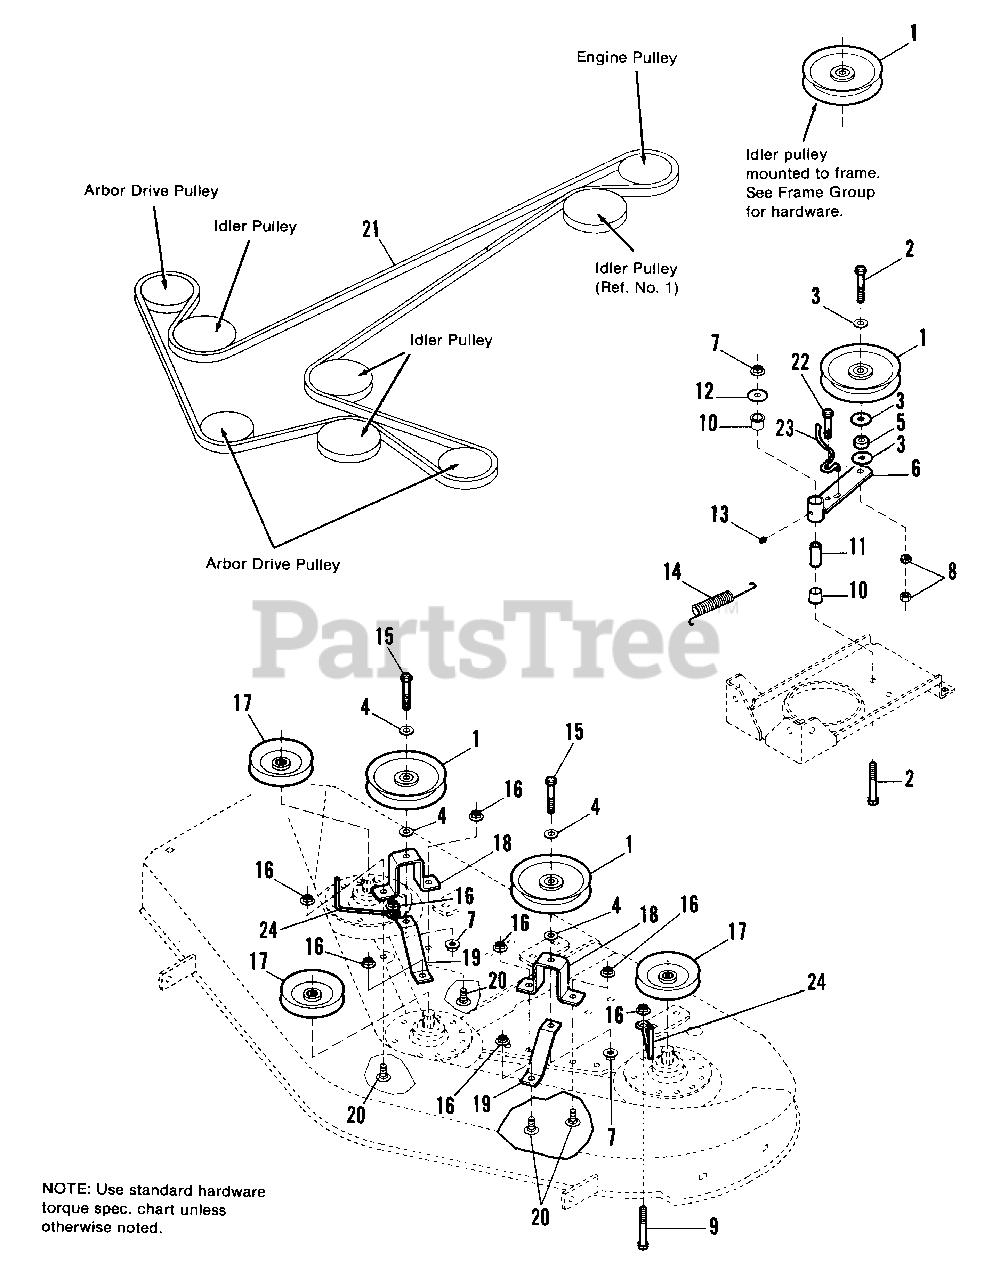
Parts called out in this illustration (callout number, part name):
1	PULLEY ASSY.
2	CAPSCREW, 3/8-16 x 2-1/4
3	WASHER, 5/16
4	WASHER, 3/8
6	ARM ASSY., Clutch
7	NUT, Hex, Whizlock 3/8-16
8	NUT,Jam Lock, 3/8-16
9	CAPSCREW, Taptite, 5/16-18 x 1-1/4
12	WASHER, 3/8
13	FITTING, Grease
15	CAPSCREW, Hex, 3/8-16 x 1-3/4
16	NUT, Flange, Whizlock, 5/16 x 18
17	PULLEY ASSY., Arbor
18	SUPPORT, Idler
20	CARRIAGE BOLT, 5/16-18 x 3/4
21	BELT, Drive, 42"
22	SCREW, Taptite, 5/16-18 x 3/4
23	STOP, BELT
